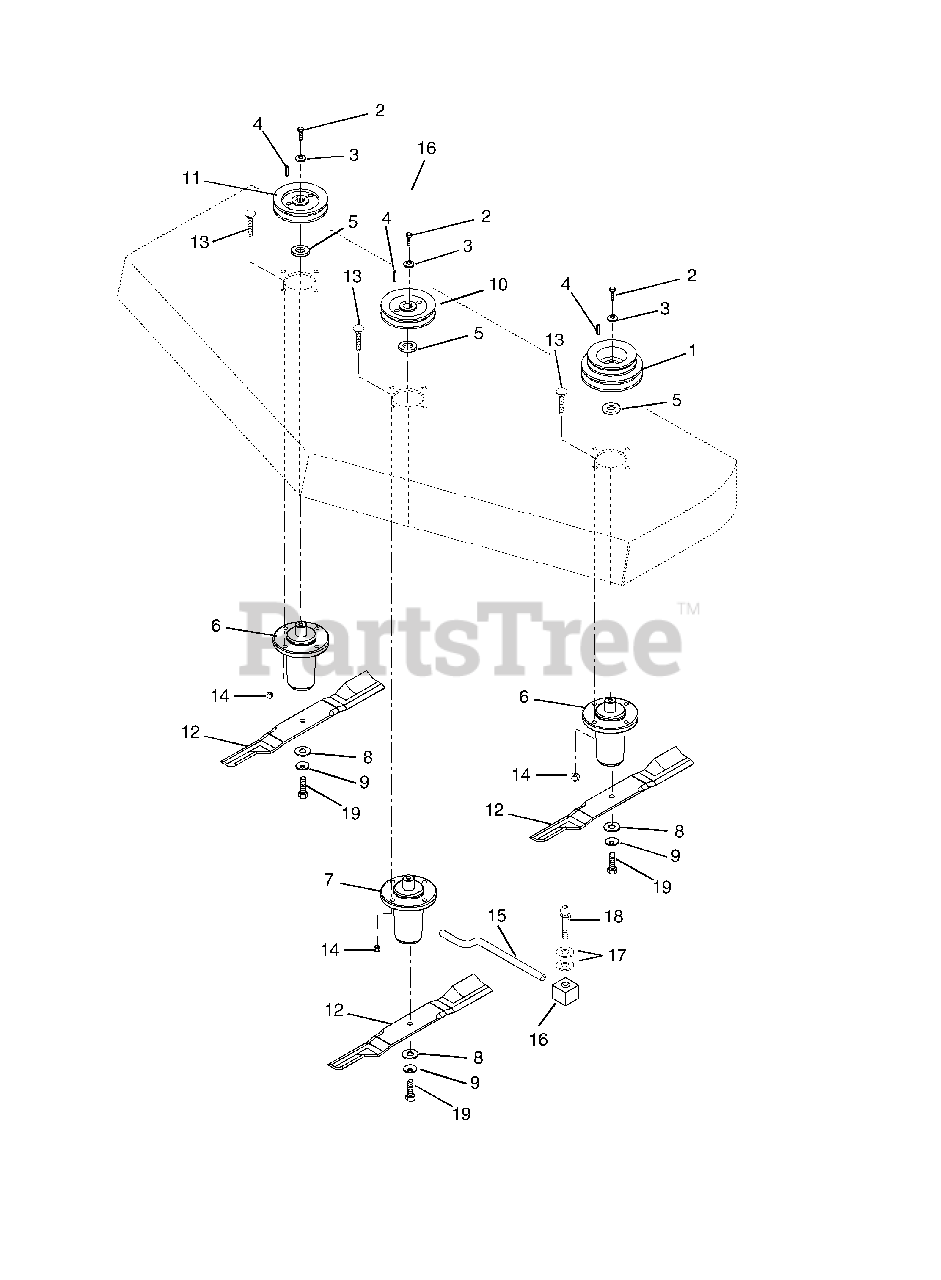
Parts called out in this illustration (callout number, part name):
1	Pulley,Double V 4.50,6.00 x 1.004
2	Bolt-Hex .38-16 x 1.00 Grade 8 with Epoxy Patch
3	Washer, Cupped, Serrated .375
4	Key-Square .25X1.00 x .25 SAE 860 or SAE 1035
5	Slinger, Dust
6	Maintenance Free Spindle Assembly
7	Maintenance Free Spindle Assembly
8	Washer,Flat .64 x 1.81 x .250
9	Washer-Bellville .63 x 1.625 x .14
10	Weldment, Spindle Sheave
11	Weldment, Pulley-V 5.50 x 1.004 with Key
12	Mower Blade Tungsten Carbide
13	Bolt-Round Head Square Neck .38-16 x 1.50 Grade 5
14	Nut-Locking-Nylon .38-16
15	Grease Tube
16	Grease Fitting
17	Washer-Flat-Steel .406 x .812 x .065
18	Fitting-Lube .12 x 65 x 1.18
19	Bolt, Blade
